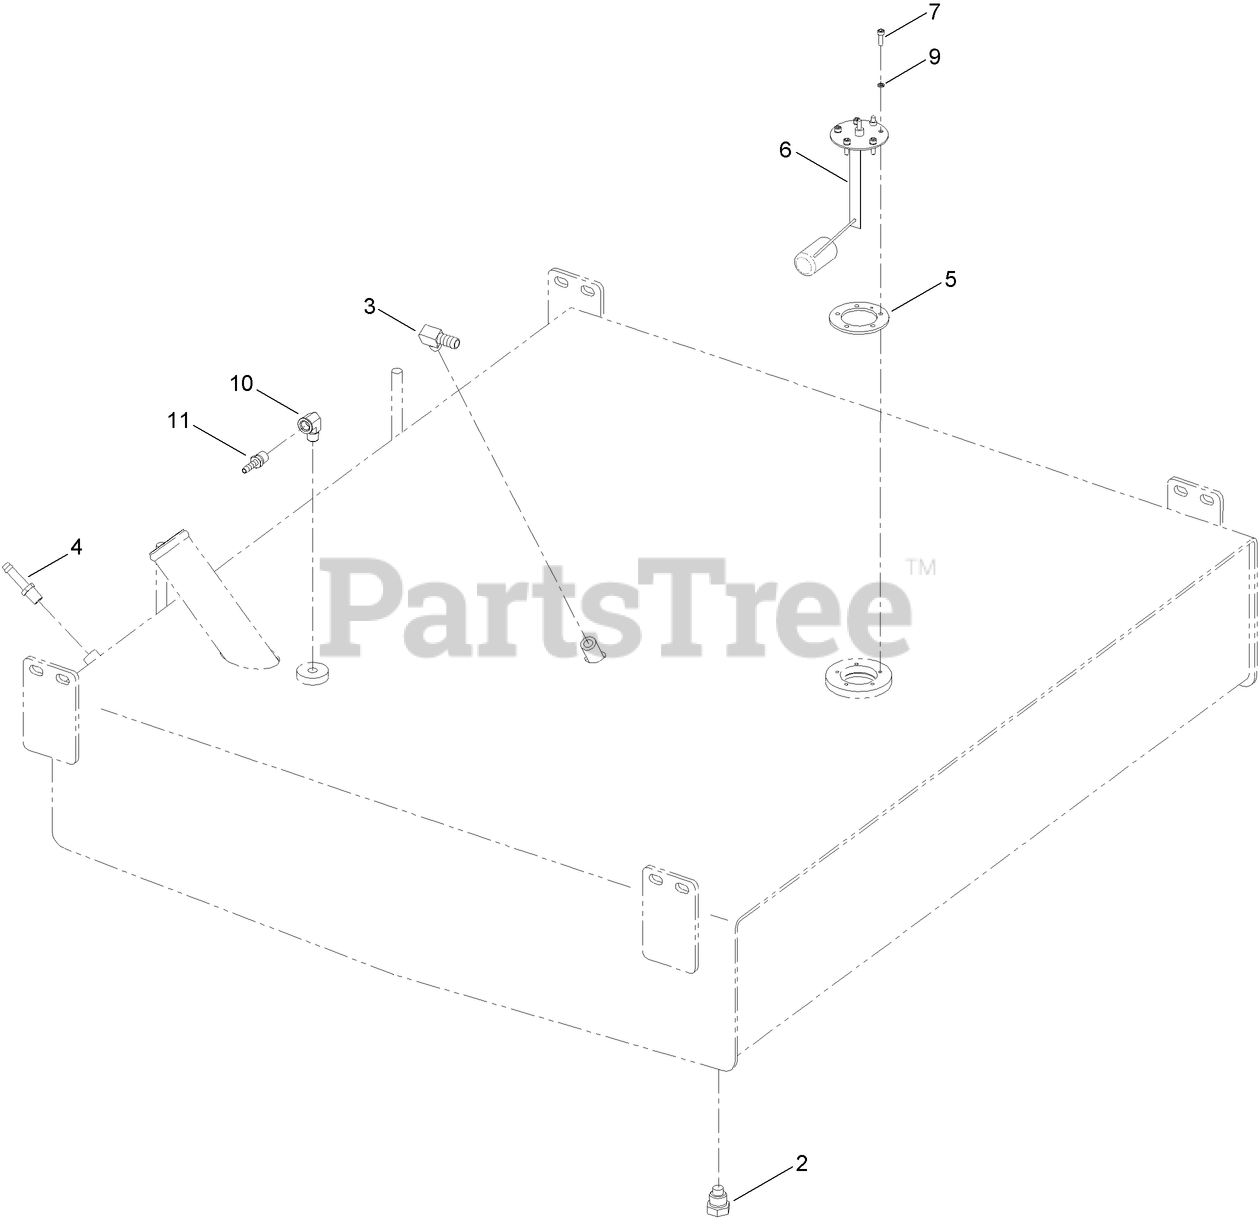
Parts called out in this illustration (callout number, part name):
2	PLUG-HEX, MAGNETIC
3	FITTING-ELBOW, 90
4	STEM-STRAIGHT, BEAD
5	GASKET-SENDING UNIT
6	SENDER-FUEL
7	SCREW-HSH
9	WASHER-LOCK
10	FITTING-ELBOW, 90
11	FITTING-STRAIGHT
